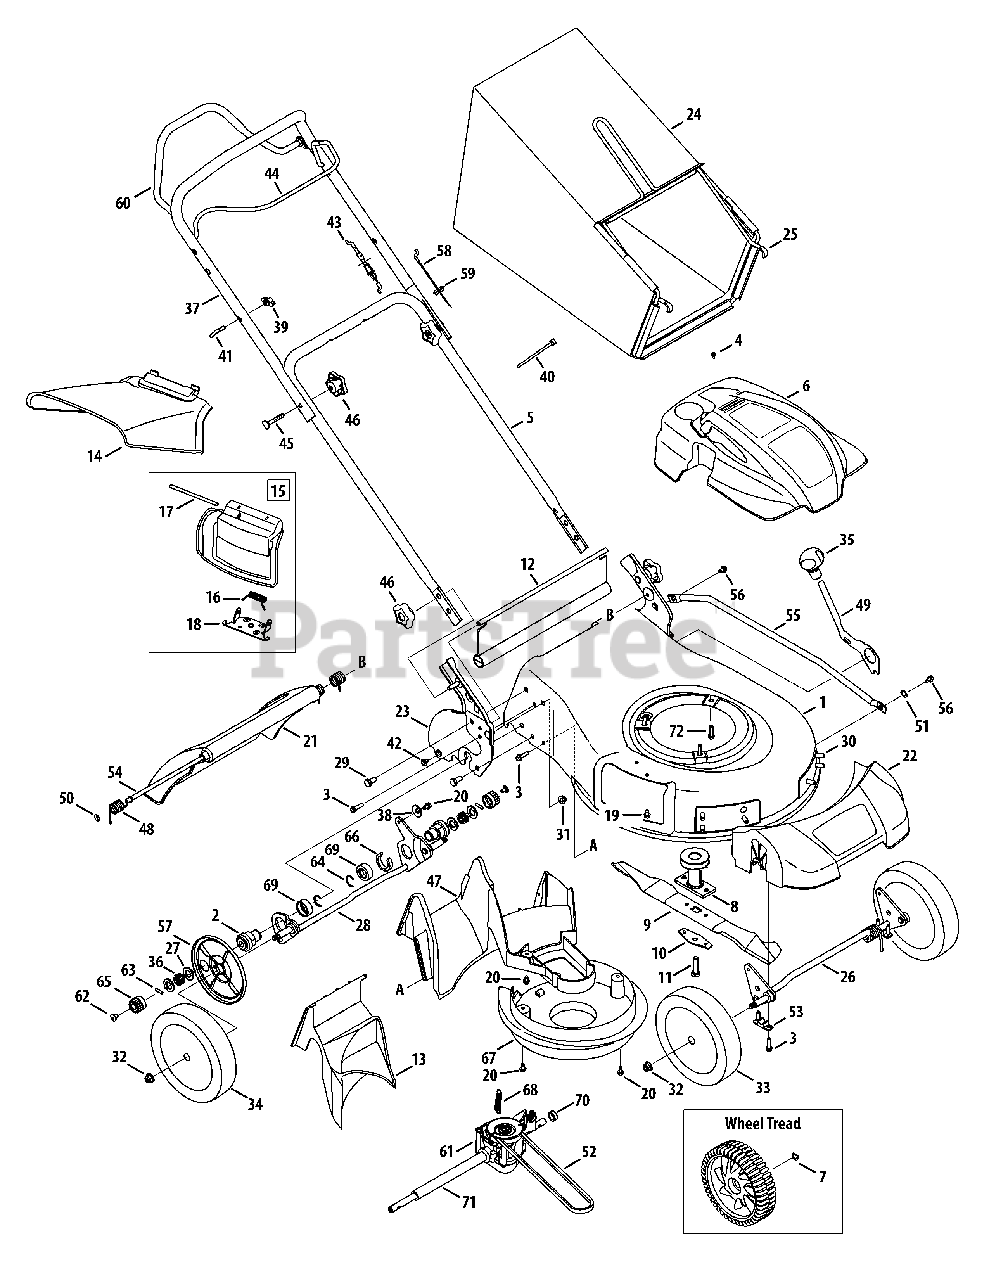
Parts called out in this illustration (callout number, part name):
2	Transmission Support Bearing
3	Screw, 1/4-15 x 1.000
4	Screw, HL, #12-16 x 1.00
5	Lower Handle
6	Engine Shroud
7	Washer, Wave, .510 x .750 x .017
8	Blade Adapter
9	Mulching Blade
10	Blade Bell Support
11	Screw, 3/8-24 x 1.50
12	Trailing Shield
13	Rear Mulch Plug
14	Side Discharge Chute
15	Mulch Plug (Incl. 16-18)
16	Torsion Spring
18	Chute Deflector Adapter
22	Front Cover
23	Handle Bracket - RH
23	Handle Bracket - LH
25	Grass Bag Frame
26	Front Bracket Assembly
27	Washer, Flat, .508 x 1.00 x .020
28	Self Propelled Bracket Ass’y
29	Hhcs, 5/16-18 x .625
30	Screw, 5/16-14 x .750
31	Nut, Flange Lock, 5/16-18
32	Nut, Flange Lock, 3/8-16
33	Front Wheel
34	Rear Wheel
36	Wave Spring
37	Upper Handle
38	Washer, Bell, .340 x .872 x .060
40	Cable Tie
41	Rope Guide
42	Screw, #10-16 x .500
43	Control Cable
44	Blade Control
45	Bolt Carriage, 5/16-18 x 2.0
47	Rear Baffle
48	Door Torsion Spring - RH
48	Door Torsion Spring - LH
49	Spring Lever
51	Washer, Wave, .385 ID x .598 OD
53	Bushing, Lock, .505 Dia. X .62
54	Rear Door Pivot Rod
55	Cross Bracket
56	Screw., Shldr., 1/4-20 x .50
57	Wheel Dust Cover
58	Drive Cable
60	Drive Control
61	Transmission
62	Screw, 1/4-20 x .390
63	Dowel Pin
64	Retainer Ring
65	Spur Gear - RH
65	Spur Gear - LH
66	Spacer, Clip
67	Engine Baffle
68	Exten. Spring, .429OD x 2.515
69	Bearing Support Spacer
70	Sleeve Spacer, .550ID x .340 Lg.
71	Sleeve Spacer, .550ID x 7.97 Lg.
72	Screw, 3/8-16 x 1.00
